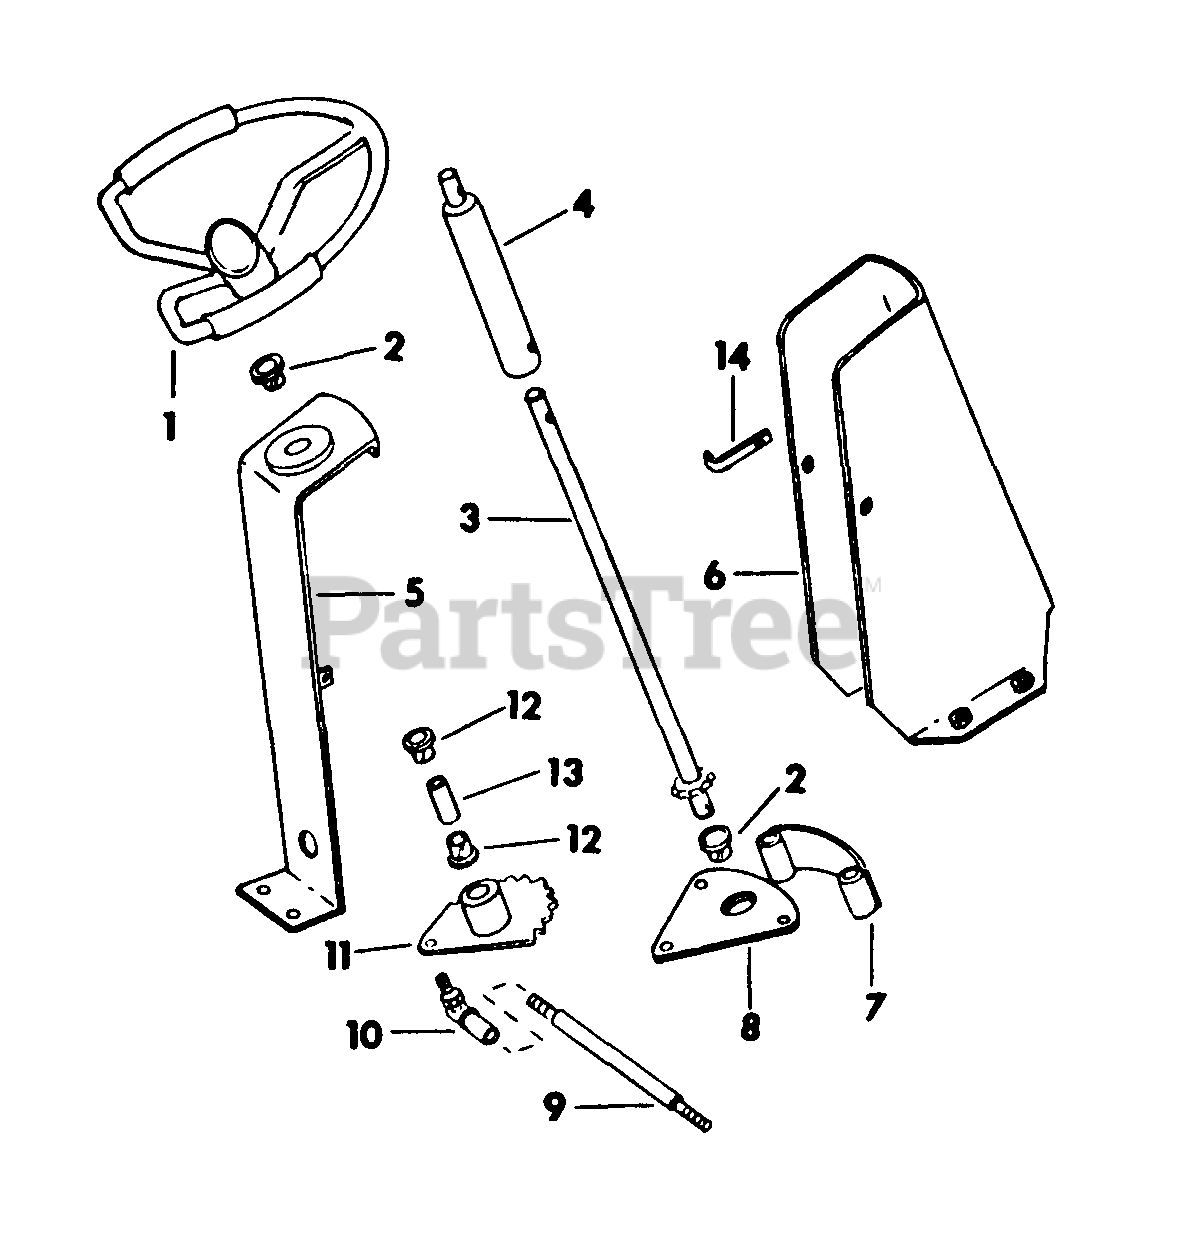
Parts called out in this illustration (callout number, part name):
1	WHEEL, STEERING
2	BEARING, STEERING SHAFT
3	SHAFT ASSY, LOWER STEERING
4	SHAFT, UPPER STEERING
5	SUPPORT ASSY, STEERING
6	SHROUD ASSY STEERING SUPPORT
7	COVER, FRT STEERING GEAR
8	COVER ASSY, STEERING GEAR
9	STUD, DRAG LINK ROD
10	JOINT, 3/8-24 BALL
11	GEAR ASSY, STEERING DRAG LINK
12	BEARING, STEERING GEAR
13	BUSHING, STEERING GEAR DRAG LINK
